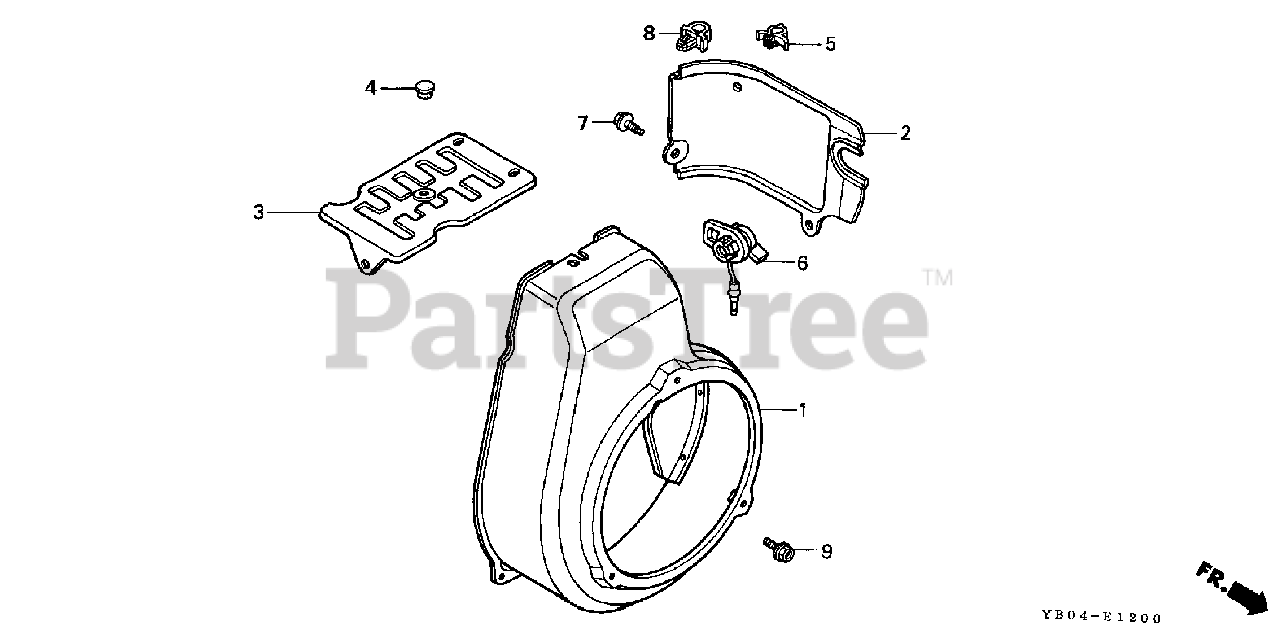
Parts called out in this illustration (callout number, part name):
1	COVER, FAN *R8* (BRIGHT RED) (NOT AVAILABLE)
3	COVER, TOP
4	GROMMET, TOP COVER
5	CLIP, IGNITION WIRE (8MM)
6	SWITCH ASSY., ENGINE STOP
7	BOLT, FLANGE (6X12) (CT200)
9	BOLT, FLANGE (6X12)
